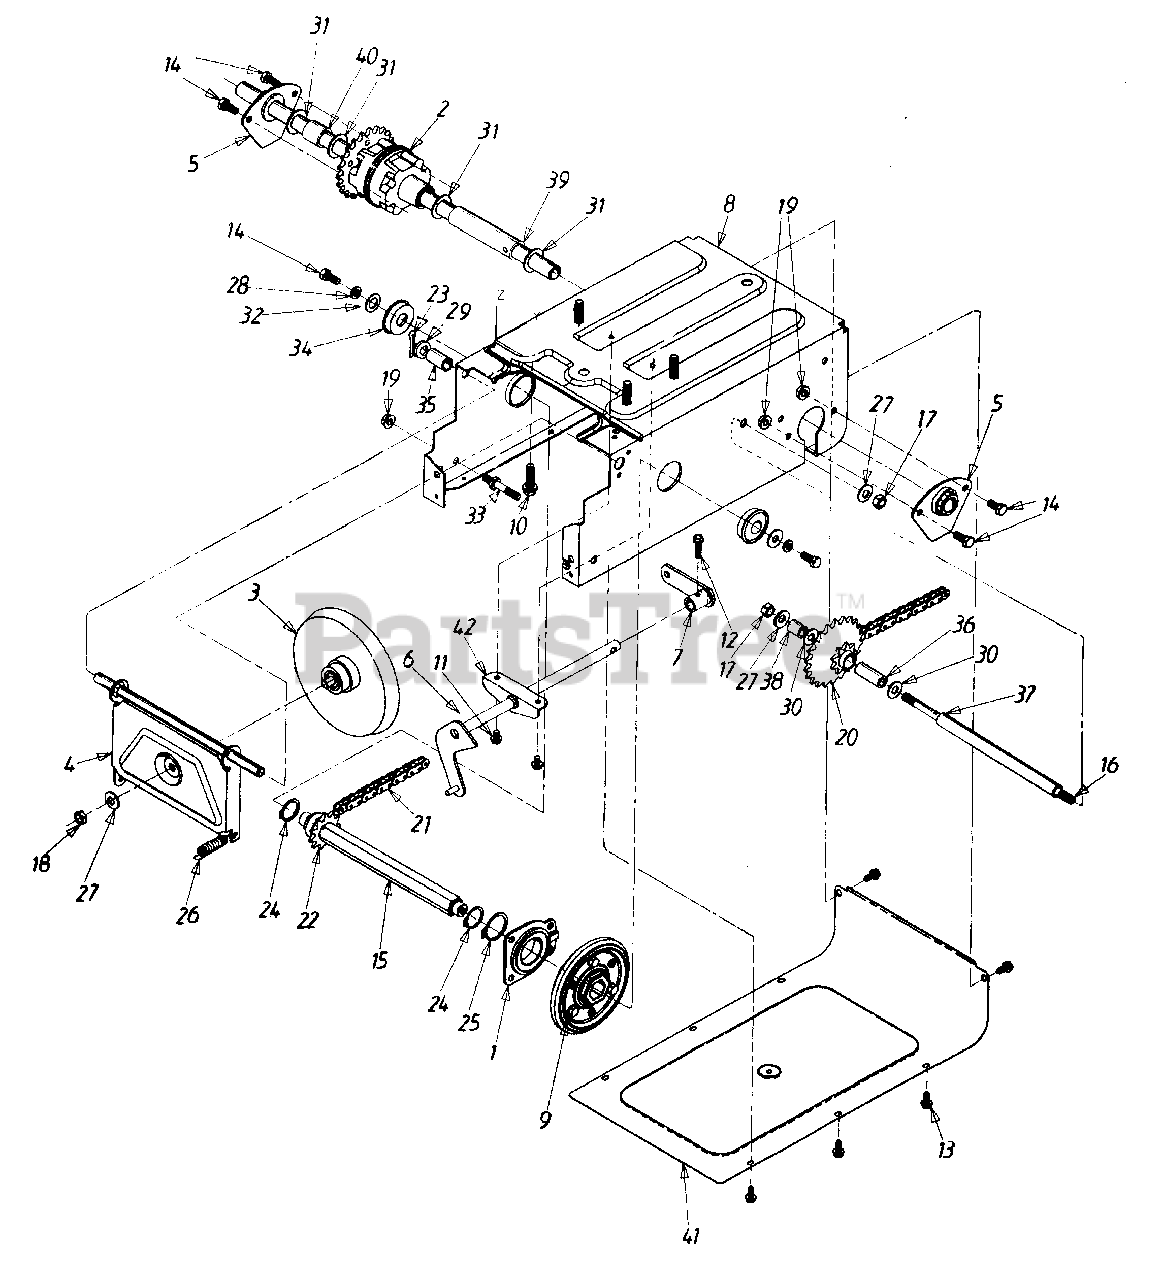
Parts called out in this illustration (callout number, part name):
1	BEARING ASSY - FRICTION WHEEL
2	DIFFERENTIAL ASSY COMP.
3	DISC - FRICTION WHEEL ASSY COMP.
6	SHAFT ASSY - SHIFT
9	WHEEL ASSY - FRICTION
10	SCREW - HEX SELF-TAP
11	SCREW - HEX WASHER
12	SCREW - HEX WASHER
13	SCREW - HEX
14	SCREW - HEX
15	SHAFT - HEX
16	SHAFT - JACK
17	NUT - HEX
18	NUT - HEX JAM
19	NUT - HEX FLANGE LOCK
20	SPROCKET & HUB
21	CHAIN
22	SPROCKET 11T
23	PIN - COTTER
24	RING - SNAP
25	RING - SNAP
26	SPRING - EXTENSION
27	WASHER - BELL
28	WASHER - LOCK
29	WASHER - FLAT
30	WASHER - FLAT
31	WASHER - FLAT
32	WASHER - FLAT
33	BOLT - IDLER
34	BEARING - BALL
35	SPACER
36	SLEEVE
37	SPACER
38	SPACER
39	SPACER
40	SPACER
